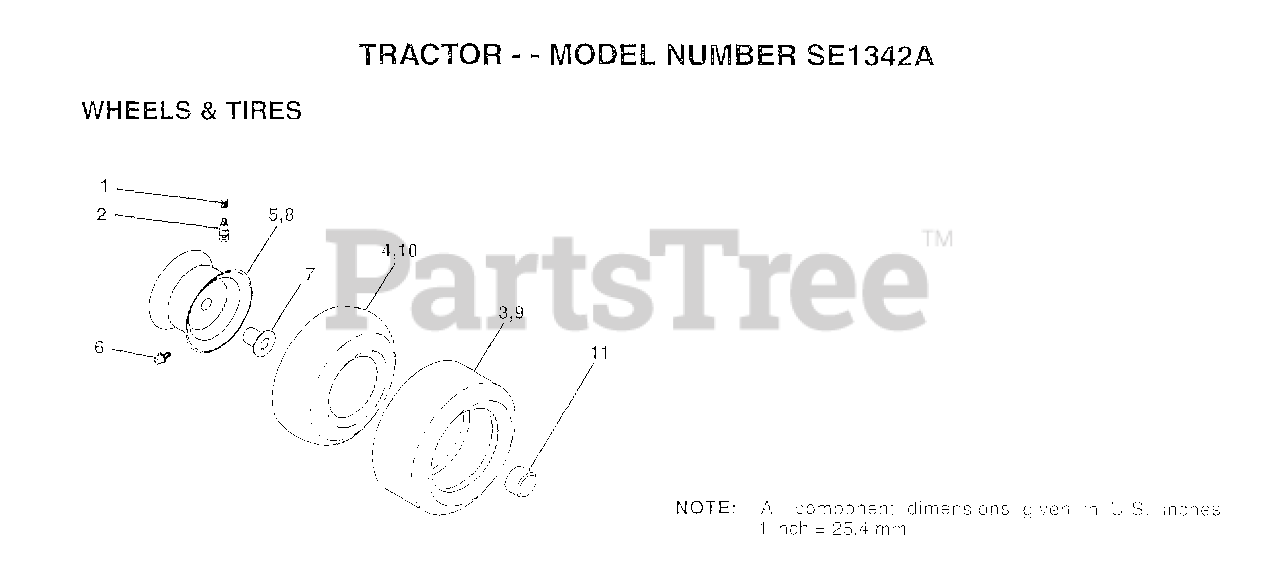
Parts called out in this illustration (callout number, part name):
1	VALVE CAP
2	VALVE STEM LT
4	TUBE.5.3/4.5/6
5	"RIM ASM 6"" FRT"
6	FITTING LT
7	"FLANGE, BEARING"
8	"RIM AS 8"" REAR"
9	TIRE.20X8-8
10	TUBE.18X9.5-8
11	HUB CAP
